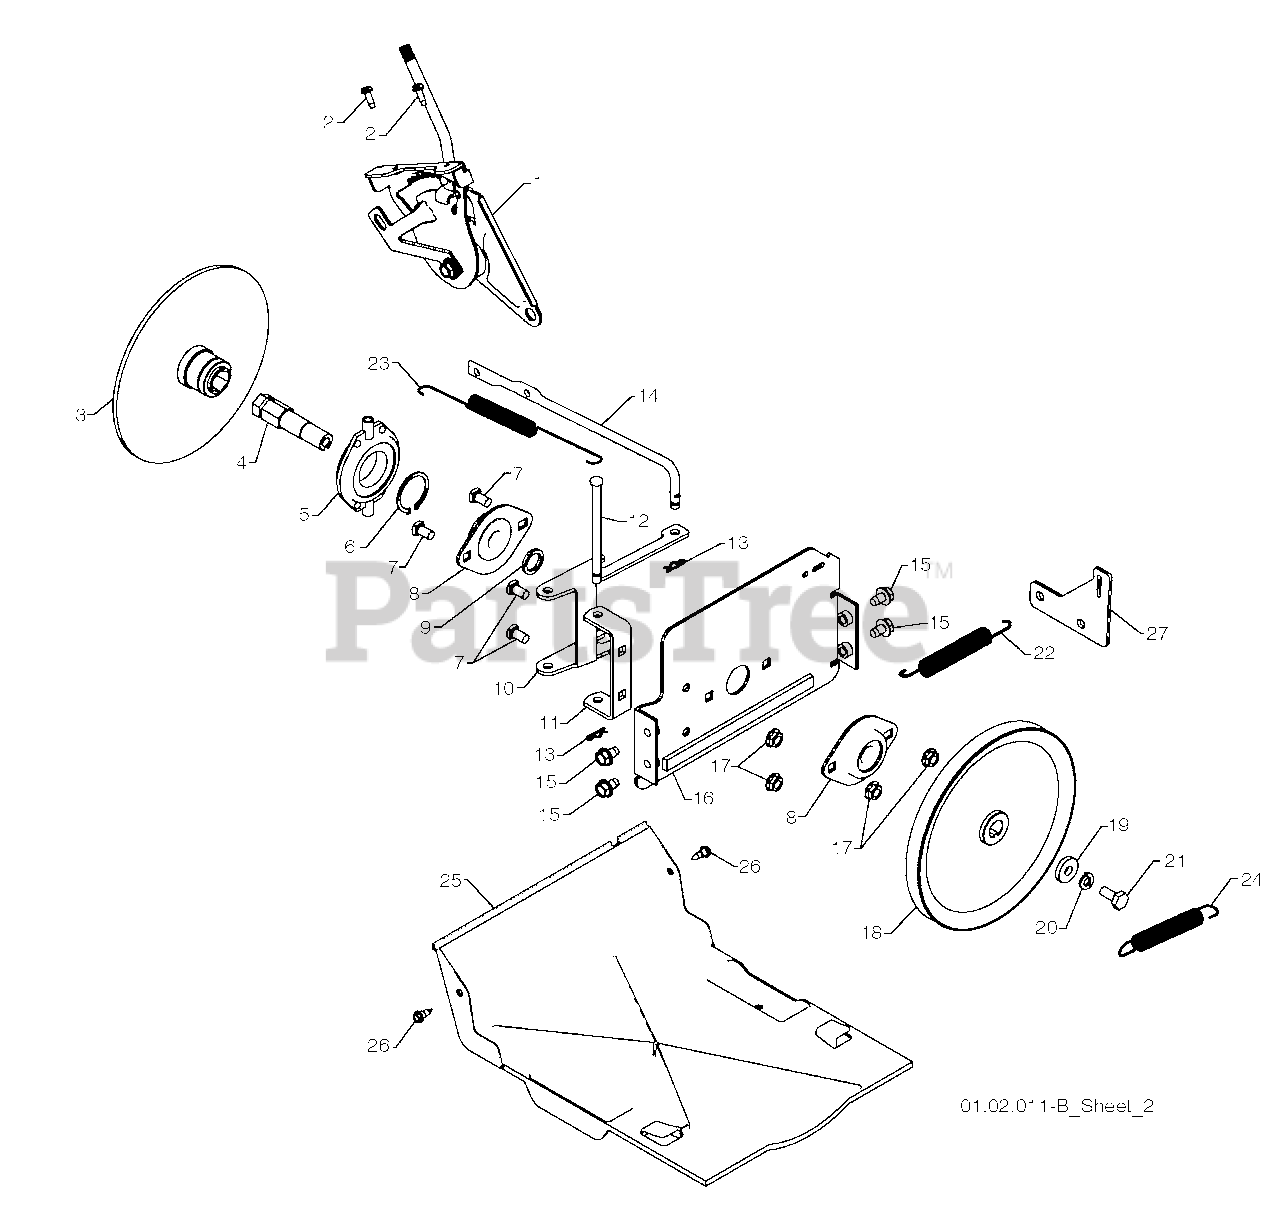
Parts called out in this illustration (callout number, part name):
1	SPEED SELECTOR HEAD ASSEMBLY
2	SCREW 10-24 X .625
3	DRIVE PLATE WELDMENT
5	TRUNNION BEARING ASSEMBLY
6	RETAINER
7	CARRIAGE BOLT 5/16-18 X .625
8	FLANGE BEARING
10	LEVER SHIFTER PLATE
11	SHIFTER SUPPORT BRACKET
14	CLUTCH ROD
15	BOLT 5/16-18 X .500
16	DRIVE MOUNT PLATE
17	NUT 5/16-18
18	TRACTION PULLEY
20	LOCKWASHER 5/16
21	SCREW 5/16-18 X .750
22	TRACTION SPRING
23	RETURN SPRING
24	BRAKE SPRING
25	BOTTOM PAN
26	SCREW 10-24 X .625
27	TRACTION SPRING BRACKET
